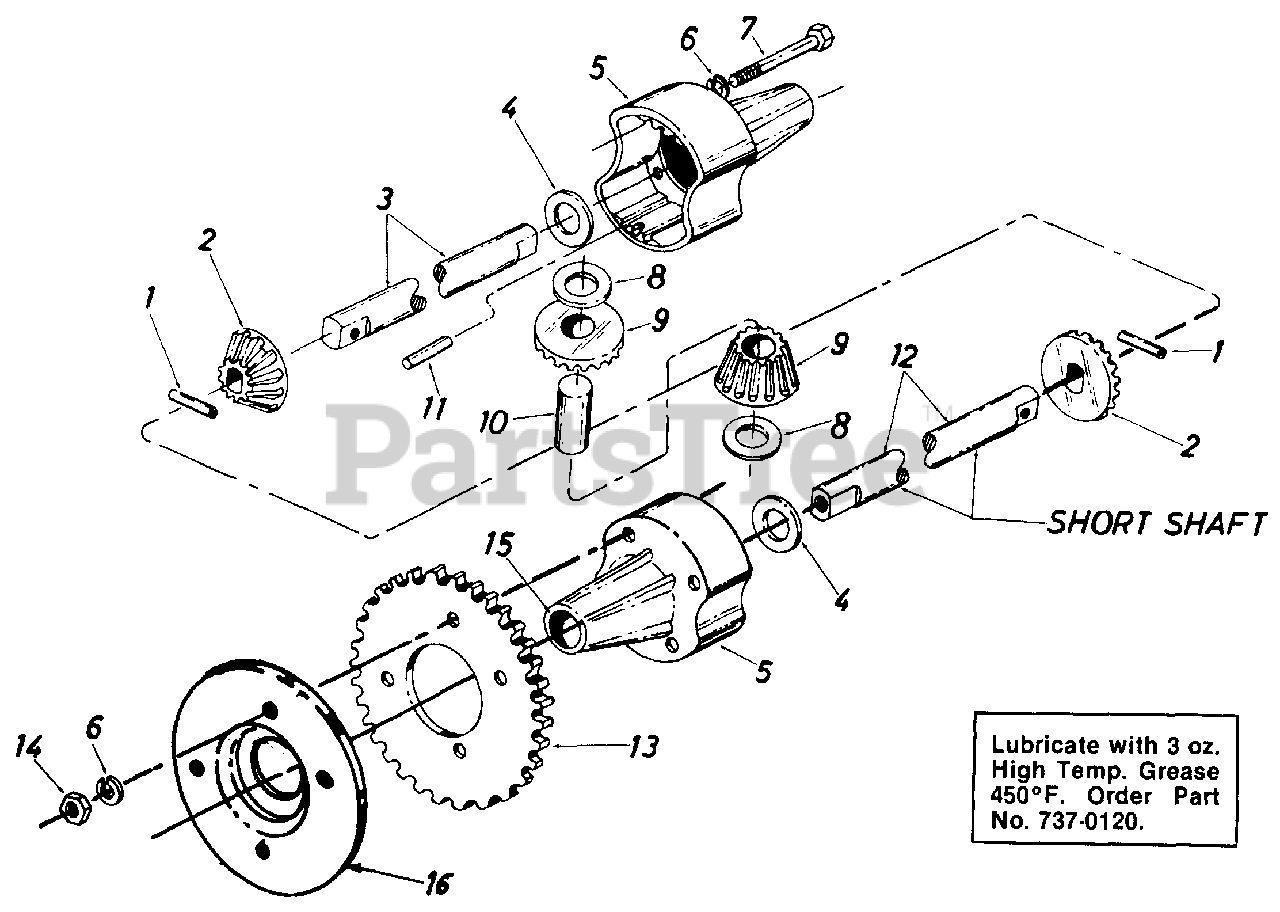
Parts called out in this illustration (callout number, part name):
1	Spring Pin Spiral 3/16" Dia. x 1.00" Lg.
2	Gear - Double "D" Hole
3	Shaft - Long - 19.81" Lg.
4	Fl-Wash. .760 I.D. x 1.49 O.D.
5	Housing Half
6	L-Wash. 5/16" I.D.
7	Hex Bolt 5/16-24 x 4.00" Lg.
8	Fl-Wash. .640 I.D. x .24 O.D.
9	Gear - Round Hole
10	Drive Pin
11	Dowel Pin 3/16" Dia. x .62" Lg.
12	Shaft - Short - 8.52" Lg.
13	Sprocket - 48 Teeth
14	Hex Cent. L-Nut 5/16-24 Thd.
15	Flange Bearing
16	Brake Disc
